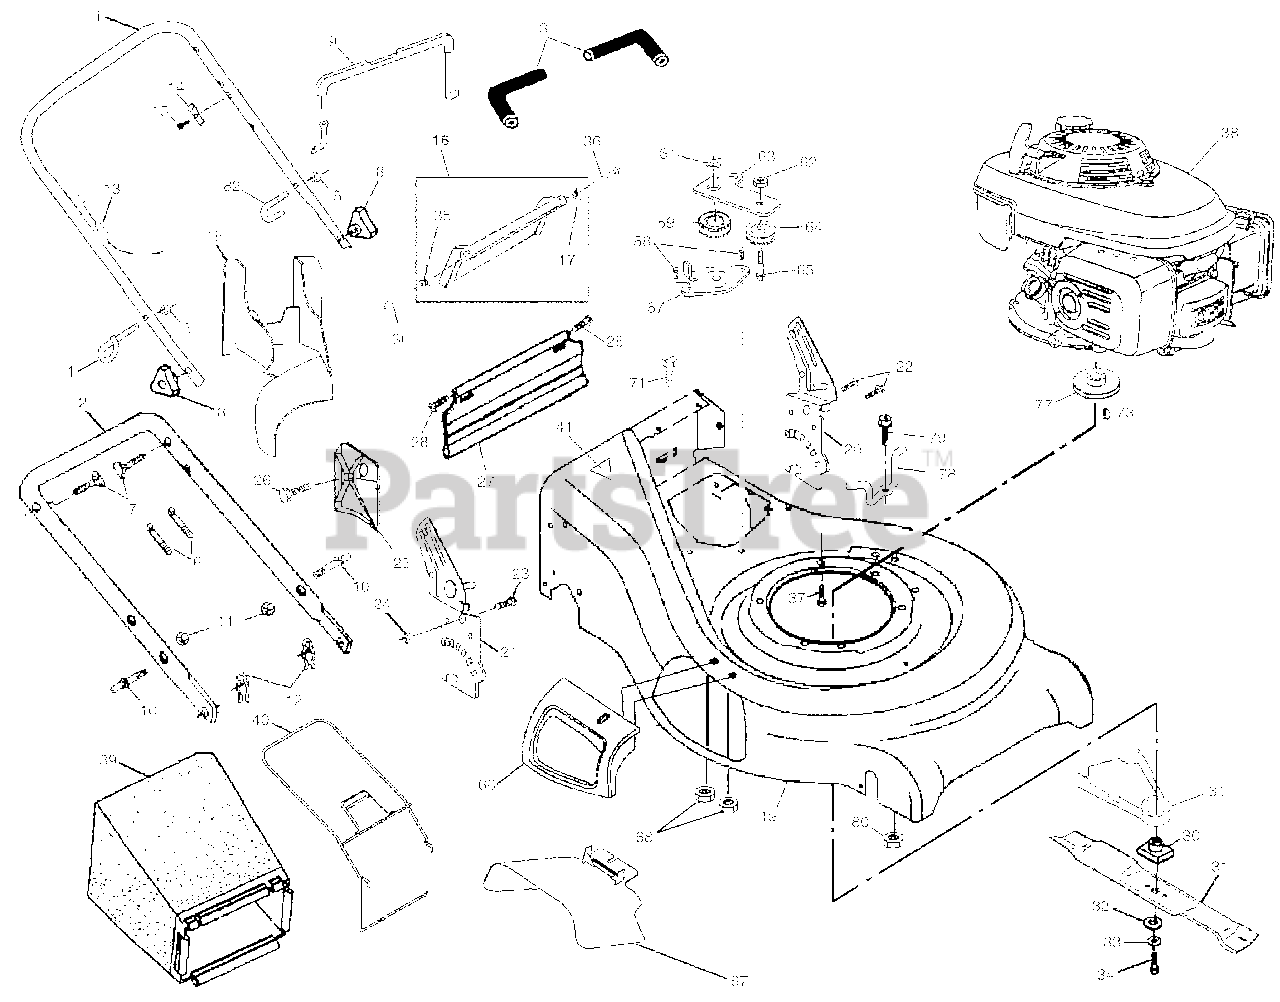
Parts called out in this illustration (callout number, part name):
1	Handle, Upper
2	Handle, Lower
3	Grip, Handle, Foam, Smooth
4	Guide, Rope, Side
5	Nut, Hex Lockwasher Insert 1/4-20
6	Wire, Tie
7	Bolt, Handle 5/16-18 x 1.75
8	Knob, Handle
9	Bail, Flat, Auto-Walk, Orange
10	Bolt, Carriage
11	Nut, Hex, Centerlock 5/16-18 UNC
12	Cotter, Hairpin
13	Engine Zone Control Cable
14	Bracket, Upstop
16	Kit, Door Rear
17	Spring, Rear Door, LH
18	Plug, Mulcher
19	Kit, Housing
20	Handle Bracket Assembly, LH
21	Handle Bracket Assembly, RH
22	Screw, Hex Washer Head
23	Bolt, Hex Head 5/16-18 x 5/8
24	Nut, Hex, with Lock Washer Insert 5/16-18
25	Baffle, Side
26	Screw 12 x 5/8
27	Skirt, Rear
28	Screw, Hinge 1/4-20 x 1.25
30	Adapter, Blade
31	Blade, 21"
32	Washer, Hardened
33	Lockwasher, Helical Spring 3/8
34	Screw, Hex Head 3/8-24 x 1.38
35	Spring, Rear Door, RH
36	Bolt, Rear Door
37	Bolt, Engine
39	Grass Catcher Bag
40	Grass Catcher Frame
41	Danger Decal
57	Bracket Assembly
59	Pulley Assembly, V-Groove
61	Flange Nut
62	Locknut
63	Idler Arm
64	Idler Pulley
65	Shoulder Bolt
66	Mulcher Door Assembly
67	Deflector, Discharge
73	Hi-Pro Key
77	Pulley, Engine
78	Belt Keeper
81	Debris Shield
